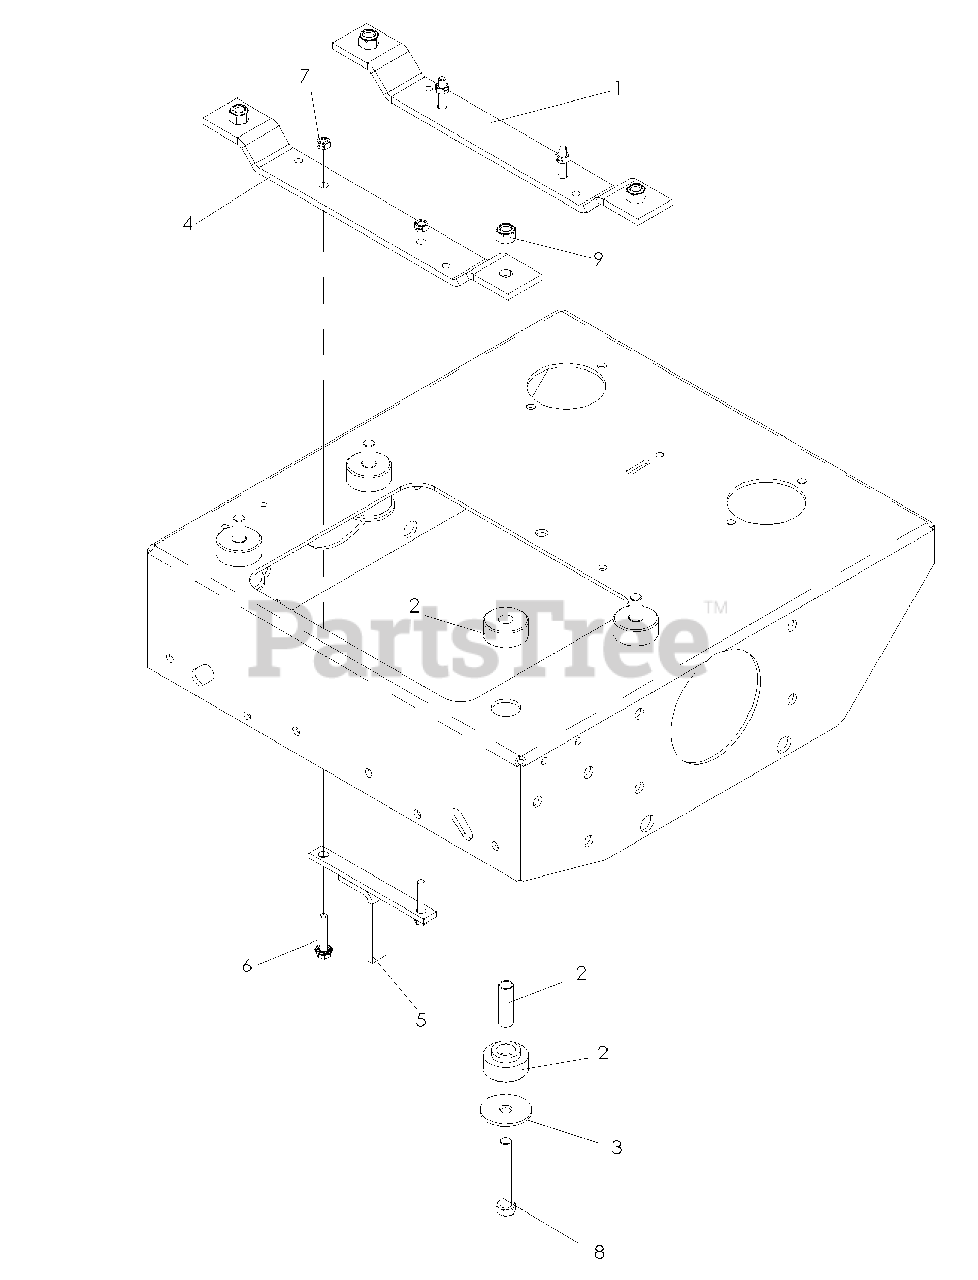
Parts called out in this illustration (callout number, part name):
1	ENGINE MOUNT
2	ISOLATORS
3	ISOLATOR WASHER
4	STRAP, ISO, REAR
5	CLUTCH TIE DOWN
6	HCS 5/16-18 X 1-3/4 SERATED
7	NUT 5/16C CENTERLOCK
8	HCS 1/2C X 3 1/4
9	NUT 1/2-13 HEX NYLOC ZD
